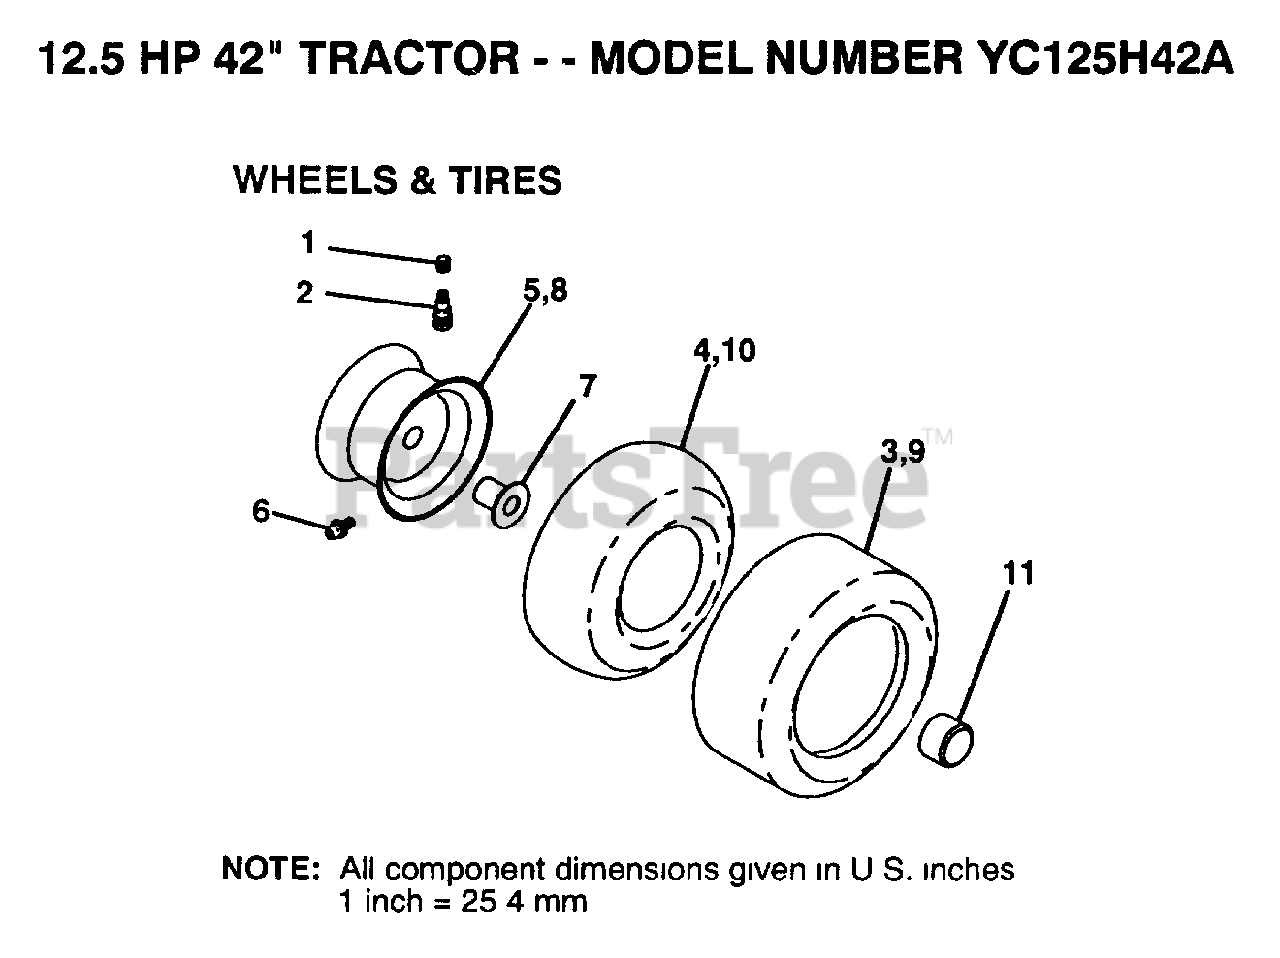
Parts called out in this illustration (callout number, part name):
1	VALVE CAP
2	VALVE STEM LT
4	TUBE.5.3/4.5/6
6	FITTING LT
7	"FLANGE, BEARING"
10	TUBE.18X9.5-8
11	HUB CAP
